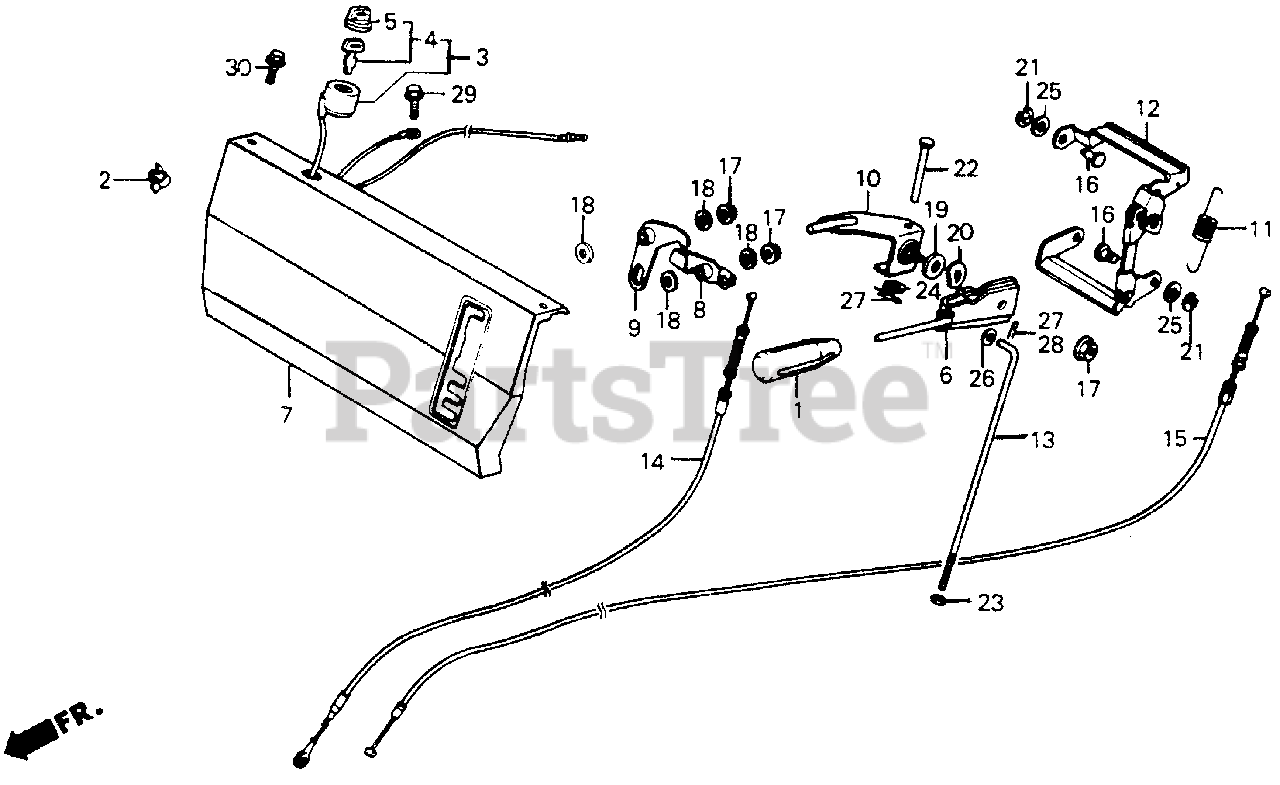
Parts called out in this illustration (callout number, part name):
1	GRIP, CHANGE LEVER
2	CLIP, IGNITION WIRE (8MM)
3	SWITCH ASSY., COMBINATION
4	KEY ASSY., COMBINATION SWITCH
5	CAP, COMBINATION SWITCH KEY
6	LEVER, CHANGE (NOT AVAILABLE)
7	PANEL, CONTROL
8	LEVER, CLUTCH DRIVE
9	LEVER, CLUTCH (NOT AVAILABLE)
10	ARM, CHANGE LEVER
11	SPRING, LEVER RETURN
12	LEVER, SUB-CHANGE
13	ROD, GEARSHIFT
14	CABLE, CHANGE (NOT AVAILABLE)
15	CABLE, SUB-TRANSMISSION
16	PIN (6MM)
17	NUT, SELF-LOCK (8MM)
18	WASHER (10MM)
19	WASHER (10X24)
20	SPRING, LEVER
21	CIRCLIP (6MM)
23	NUT, HEX. (8MM)
25	WASHER, PLAIN (6MM)
27	PIN, LOCK (6MM)
28	PIN, LOCK (8MM)
29	BOLT, FLANGE (6X12)
30	BOLT, FLANGE (6X10)
